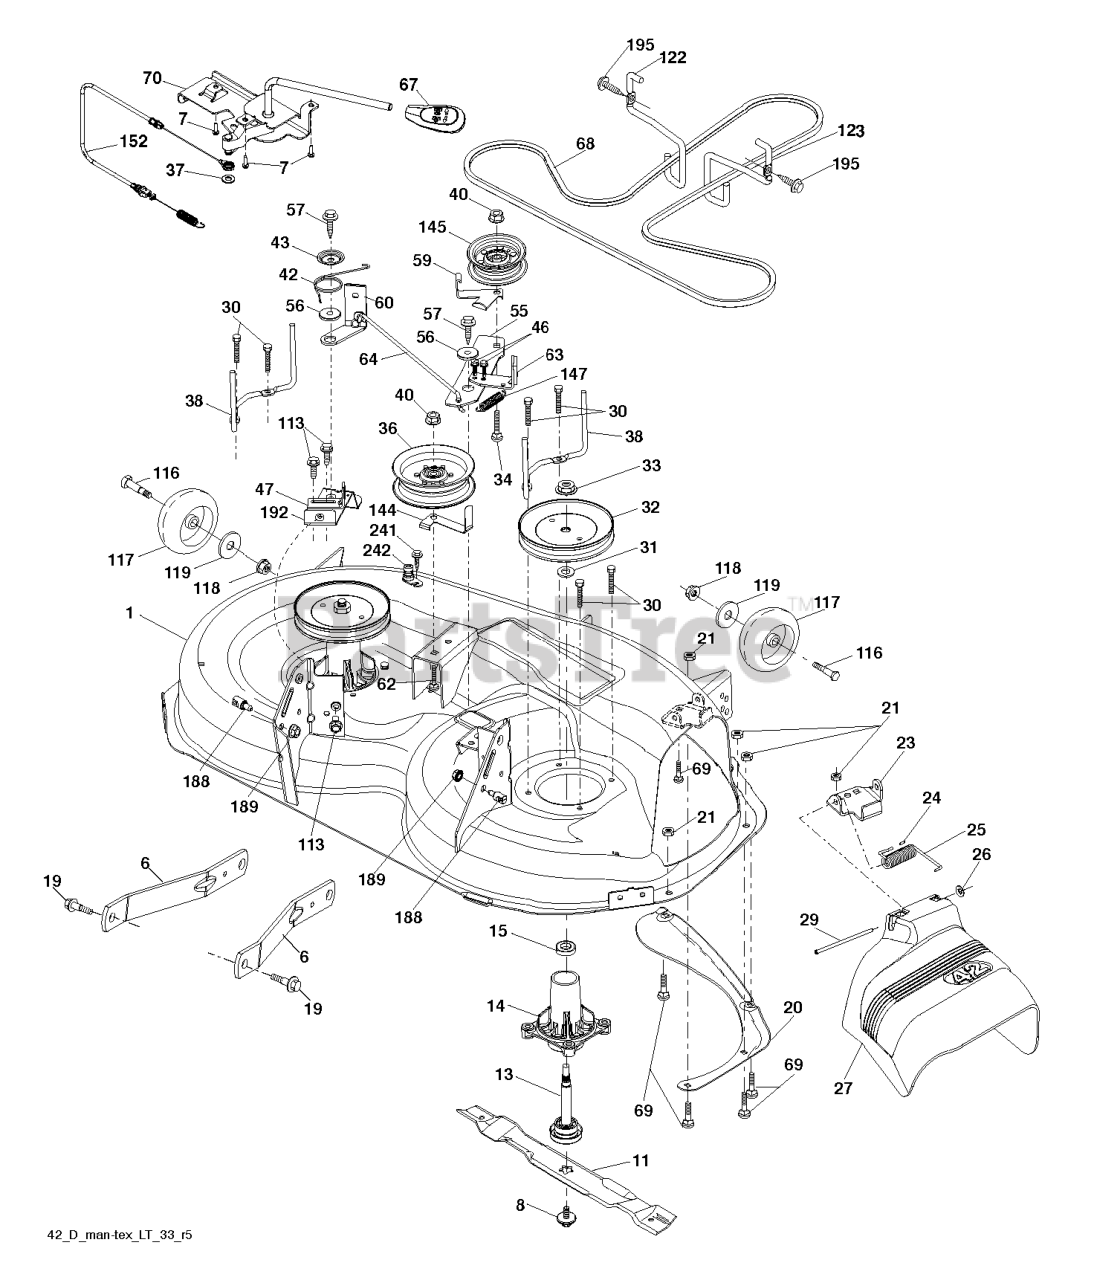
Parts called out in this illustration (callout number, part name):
1	DECK.WELDMENT.42"PAINT
6	ARM.SUSPENSION.MOWER.R
7	SCREW.#10 X 0.750.BOS
8	BOLT.WASHER.ASM.7/16-2
11	42" HI-LIFT BLADE
13	SHAFT.ASM.MDRL.N/GREASE.38
14	RP.HOUSING.MANDREL.4PT.
19	BOLT.SHOULDER
20	BAFFLE.VORTEX
21	LOCKNUT
23	BRKT.DEFLECTOR.38"2005+
24	CAP-SLEEVE LT
25	SPRING.TORSION.DEFLECT
26	NUT PUSH M
27	SHIELD.DEFLECTOR.MOWER.42"BLAC
29	ROD.HINGE
30	SCREW, WASHER HEAD
31	WASHER.SPACER.MANDREL
32	PULLEY.MANDREL.5.438.PD
33	NUT.FLANGE.LOCK.TOP
34	BOLT.3/8-16X1.50
36	PULLEY.IDLER.2006
37	WASHER
38	KEEPER.BELT.MANDREL.PULLEY
40	NUT LOCK FLG 3/8-16 UNC
42	SPRING.TORSION.BRAKE
43	SRPING.TORSION.RETAINE
46	SCREW.1/4-20X5/8
47	BRKT.CLUTCH.CABLE
55	IDLER.ARM.42"
56	SPACER.RETAINER
57	SCREW 3/8-16X1
59	GUARD, BELT
60	ARM BRAKE MOWER
63	ARM BRAKE MOWER
64	LINKAGE.BRAKE.ASM.ZINC
67	HANDLE.CLUTCH.CABLE.LT
68	BELT.DECK.DRIVE.42"
69	BOLT
70	CLUTCH.ASM.MANUAL.LT.PRED
113	BOLT.5/16HEX.WHS.HD
116	BOLT M
117	WHEEL.GAGE.HALF.SPOKED
118	NUT LOCK FLG 3/8-16 UNC
119	WASHER.5/16.FLAT.STE.STD.
122	KEEPER BELT ENGINE LH
123	KEEPER BELT RH
144	KEEPER.BELT.MOWER
145	PULLEY.IDLER.48"PRIMARY
147	RETURN SPRING
152	CABLE.CLUTCH.MANUAL.
188	STUD.FASTNER.W/ANTI-ROTATE
189	NUT LOCK HEX FLANGE 5/16-18
192	BRKT.BRAKE.STAND.LH.
195	SCREW, 3/8-16X3/4
241	SCREW.TT.#10-32X.5.3/8.FLANGE
242	PORT.WASHOUT
